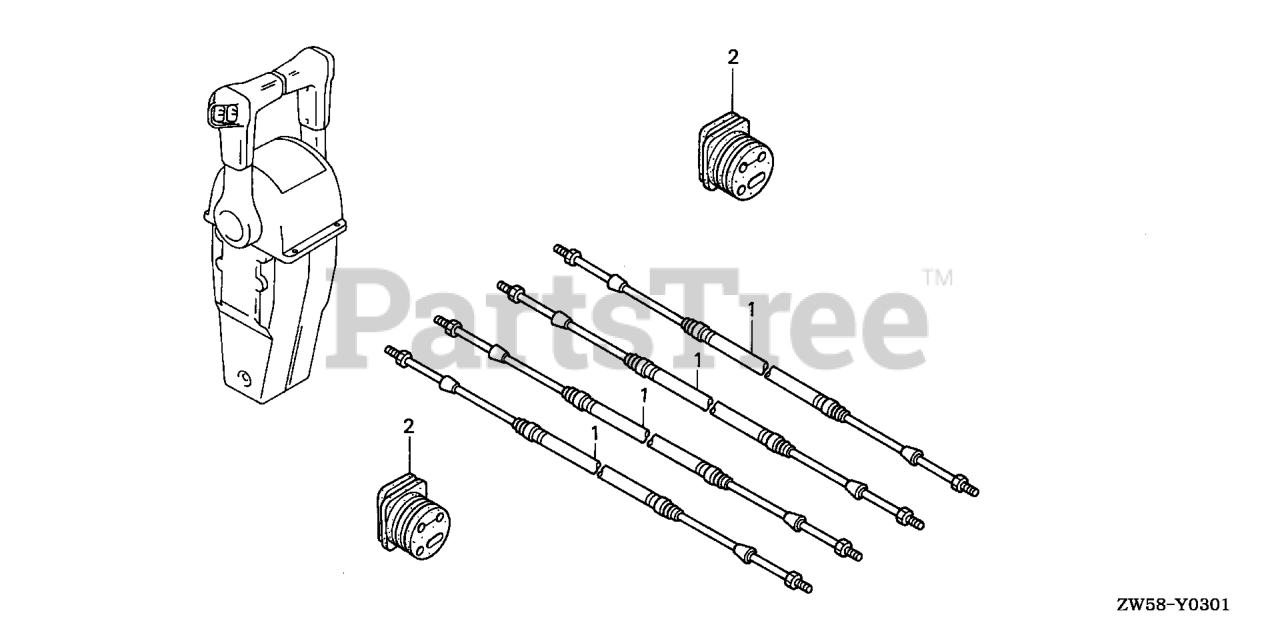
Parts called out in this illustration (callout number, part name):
1	CABLE, REMOTE CONTROL (10'') (LOW FRICTION)
1	CABLE ASSY., PUSH-PULL (33C-5FT)
1	CABLE, REMOTE CONTROL (11'') (LOW FRICTION)
1	CABLE ASSY., PUSH-PULL (33C-6FT)
1	CABLE, REMOTE CONTROL (12'') (LOW FRICTION)
1	CABLE ASSY., PUSH-PULL (33C-7FT)
1	CABLE, REMOTE CONTROL (13'') (LOW FRICTION)
1	CABLE ASSY., PUSH-PULL (33C-8FT)
1	CABLE, REMOTE CONTROL (14'') (LOW FRICTION)
1	CABLE ASSY., PUSH-PULL (33C-9F T)
1	CABLE, REMOTE CONTROL (15'') (LOW FRICTION)
1	CABLE ASSY., PUSH-PULL (33C-10FT)
1	CABLE, REMOTE CONTROL (16'') (LOW FRICTION) (NOT AVAILABLE)
1	CABLE ASSY., PUSH-PULL (33C-11FT)
1	CABLE, REMOTE CONTROL (17'') (LOW FRICTION)
1	CABLE ASSY., PUSH-PULL (33C-12 FT)
1	CABLE, REMOTE CONTROL (18') (LOW FRICTION) (NOT AVAILABLE)
1	CABLE ASSY., PUSH-PULL (33C-13 FT)
1	CABLE, REMOTE CONTROL (1 9'') (LOW FRICTION)
1	CABLE ASSY., PUSH-PULL (33C-14FT)
1	CABLE, REMOTE CONTROL (20'') (LOW FRICTION) (NOT AVAILABLE)
1	CABLE ASSY., PUSH-PULL (33C-15 FT)
1	CABLE, REMOTE CONTROL (21') (LOW FRICTION)
1	CABLE ASSY., PUSH-PULL (33C-16FT)
1	CABLE, REMOTE CONTROL (22') (LOW FRICTION) (NOT AVAILABLE)
1	CABLE ASSY., PUSH-PULL (33C-17 FT)
1	CABLE, REMOTE CONTROL (2 3'') (LOW FRICTION)
1	CABLE ASSY., PUSH-PULL (33C-18 FT)
1	CABLE, REMOTE CONTROL (24') (LOW FRICTION) (NOT AVAILABLE)
1	CABLE ASSY., PUSH-PULL (33C-19FT)
1	CABLE, REMOTE CONTROL (25') (LOW FRICTION)
1	CABLE ASSY., PUSH-PULL (33C-20FT)
1	CABLE, REMOTE CONTROL (26') (LOW FRICTION)
1	CABLE ASSY., PUSH-PULL (33C-21FT)
1	CABLE, REMOTE CONTROL (27') (LOW FRICTION)
1	CABLE ASSY., PUSH-PULL (33C-22FT)
1	CABLE, REMOTE CONTROL (28') (LOW FRICTION) (NOT AVAILABLE)
1	CABLE ASSY., PUSH-PULL (33C-23FT)
1	CABLE, REMOTE CONTROL (2 9') (LOW FRICTION)
1	CABLE ASSY., PUSH-PULL (33C-24FT)
1	CABLE, REMOTE CONTROL (30') (LOW FRICTION) (NOT AVAILABLE)
1	CABLE ASSY., PUSH-PULL (33C-25FT)
1	CABLE, REMOTE CONTROL (31') (LOW FRICTION)
1	CABLE ASSY., PUSH-PULL (33C-26FT)
1	CABLE, REMOTE CONTROL (32') (LOW FRICTION) (NOT AVAILABLE)
1	CABLE ASSY., PUSH-PULL (33C-27FT)
1	CABLE, REMOTE CONTROL (33') (LOW FRICTION)
1	CABLE ASSY., PUSH-PULL (33C-28FT)
1	CABLE, REMOTE CONTROL (34') (LOW FRICTION)
1	CABLE ASSY., PUSH-PULL (33C-29FT)
1	CABLE, REMOTE CONTROL (35') (LOW FRICTION)
1	CABLE ASSY., PUSH-PULL (33C-30FT)
1	CABLE ASSY., PUSH-PULL (33C-31FT)
1	CABLE ASSY., PUSH-PULL (33C-32FT)
2	GROMMET, CASE (LOWER) (B)
